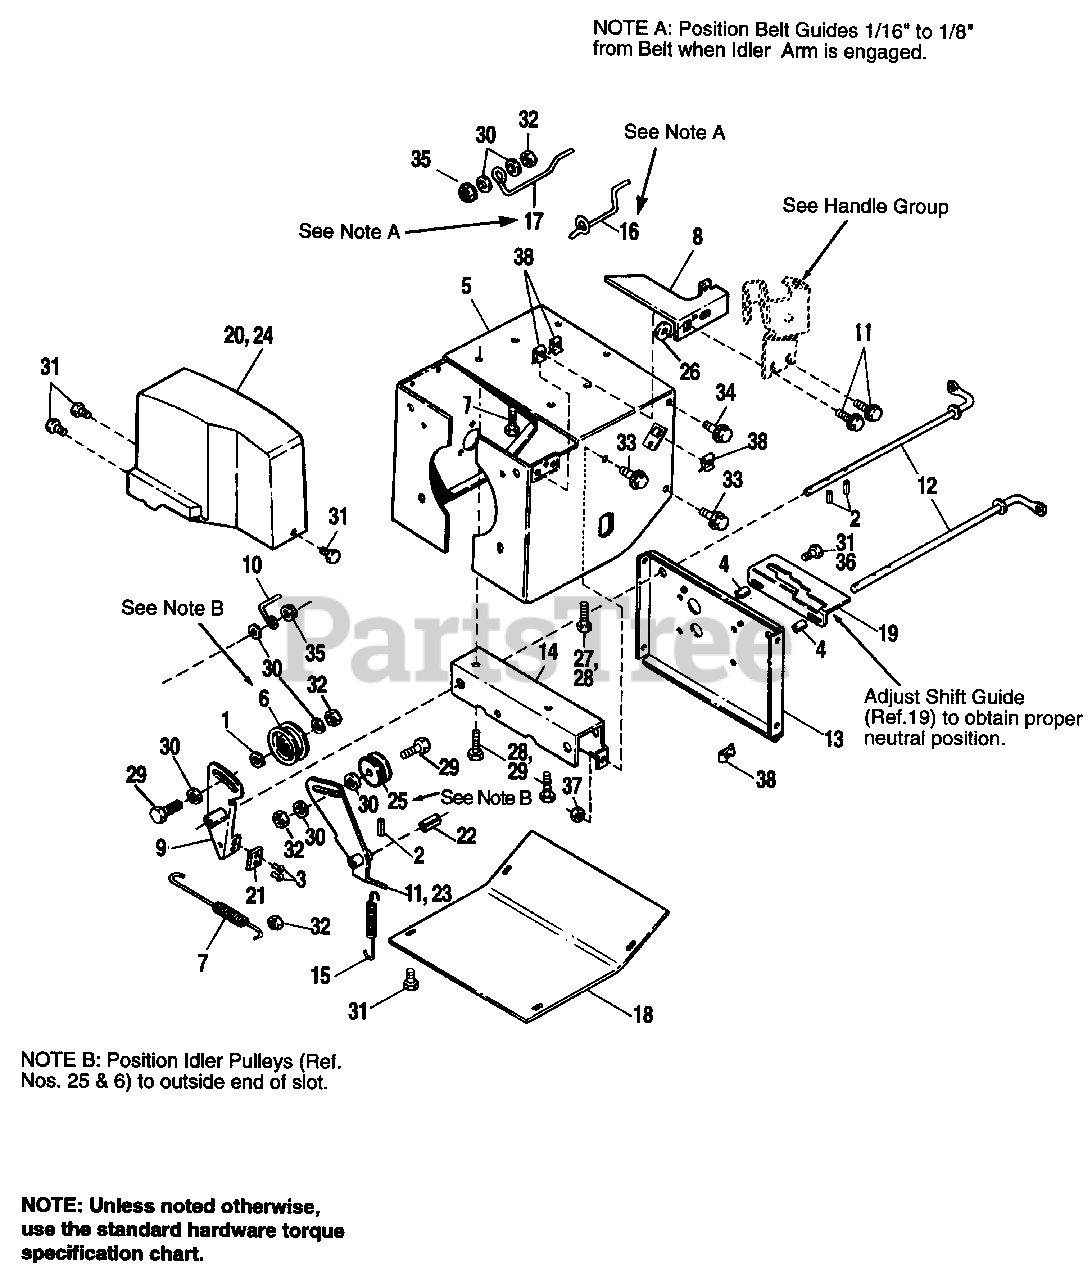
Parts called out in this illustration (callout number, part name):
4	SPACER (7 HP only)
6	PULLEY, Idler, Auger
7	SPRING, Brake Return
8	COVER, Belt
9	IDLER ARM & BRAKE ASSY. (Incl. Ref. Nos. 21 & 3)
10	GUIDE, Belt
11	IDLER ARM ASSY., Traction (5 HP only)
13	MOUNTING PLATE, Transmission
14	SUPPORT, Transmission
16	BELT GUIDE, LH
17	BELT GUIDE, RH
18	PAN, Bottom
19	GUIDE, Shift
20	GUARD, Belt (5 HP only)
21	PAD, Brake
23	IDLER ARM ASSY., Traction (7 HP only)
24	GUARD, Belt (7 HP only)
25	PULLEY, Idler (Incl. Ref. No. 1)
26	WASHER, 11/32
27	SCREW, Hex, 5/16-18 x 1-1/2 (5 HP only)
28	CAPSCREW, Hex Hd., 5/16-18 x 3/4 (7 HP only)
29	CAPSCREW, Hex, 3/8-16 x 1-1/2
30	WASHER
31	SCREW, Hex, Taptite, 1/4-20 x 1/2 (Qty. 7 on 7 HP)
32	NUT, Hex, Jam 3/8-16
33	SCREW, Hex, Flange Lock, 5/16-18 x 3/4
34	SCREW, Hex, Flange Lock, 5/16-18 x 1-1/4
35	NUT, Hex, Flange Lock, 3/8-16
36	SCREW, Hex Hd., Taptite 1/4-20 x 1-1/2 (7 HP only)
37	NUT, Hex, Flange Lock, 5/16-18
38	PALNUT, 5/16-18
